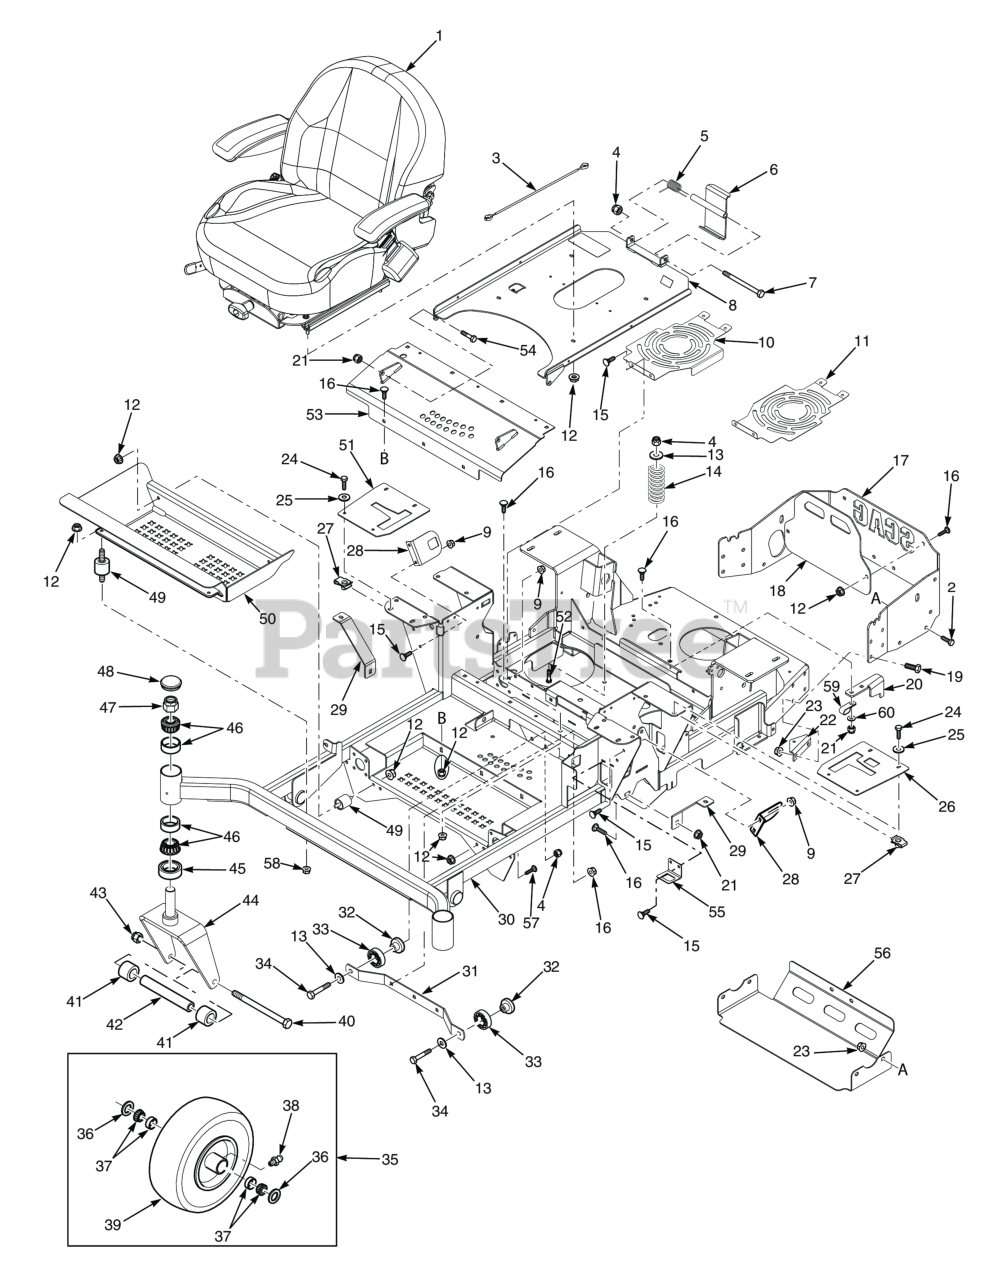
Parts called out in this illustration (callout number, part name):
1	Seat Assembly
2	Capscrew, 3/8-16 x 1.0" Serrated Flange Hex Hd
3	Cable, Seat Stop
4	HEX NUT, ELASTIC STOP LOCK, 3/8-16
5	Spring, Seat Latch
6	Weldment, Seat Latch
7	Bolt, 3/8-16 x 6.00" Hex Head
8	Seat Plate Weldment
9	NUT, 1/4-20 SERRATED FLANGE HEX HEAD
10	Fan Cover, RH
11	Fan Cover, LH
12	Nut, Serrated Flange 5/16-18 (Right Front Engine Mounting, Briggs and Kohler Only)
13	Flatwasher, 3/8" Special (.391 x .938 x .105)
14	Spring, Seat
15	Bolt, Carriage 1/4-20 x 1/2"
16	Bolt, 5/16-18 x .75 RHSN Carriage
17	Bumper, (Black)
18	Guard, Engine, (Scag Gold)
19	Bolt, Hex Head, 3/8-16 x 1 Gr. 5
20	Bracket, Anti-Rotation
21	HEX NUT, ELASTIC STOP LOCK, 3/8-16
22	Bracket, Dump Mounting
23	NUT, 3/8-16 SERRATED FLANGE HEX HEAD
24	CAP SCREW, 1/4-20 X 1" SERRATED FLANGE HEX
25	Flatwasher, 1/4" (.312 x .750 x .065")
26	Control Plate w/Decal, LH (Black)
27	Bolt, Hex Head 3/8-16 x 1"
28	Bracket, Switch Mount
29	Bracket, Tank Mount, SFZ61
30	Mainframe Assy., w/Decals (Black)- SPZ61H
31	Support, Deck Guide
32	Spacer, Bearing
33	Bearing
34	Capscrew, Hex Head 3/8-16 x 2-1/2"
35	Wheel Assembly, (Black)
36	Roller Bearing, Short
37	Bearing, Tapered Roller
38	Fitting, Grease
39	Tire, 13 x 6.50 4-Ply (61A, 72A)
40	Bolt, Hex Head 1/2-13 x 9-1/2" (61V & 72A/VS)
41	Spacer, Caster Wheel
42	Sleeve, Caster Wheel (61V, 72A/VS)
43	HEX LOCKNUT, ELASTIC STOP, 1/2-13
44	Yoke Weldment, (Black))
45	Seal, 2.00" O.D. x 1.625" Bore
46	Bearing Set
47	Nut, Elastic Stop 1.0"-14
48	Cap, Grease
49	Rubber Isolator
50	Footplate Weldment, (Black) - SPZ61
51	Control Plate w/Decal, RH (Black)
52	SHORT SQ. NECK CARRIAGE BOLT, 3/8-16 X 1-1/4"
53	Deck Lift Cover w/Decal, (Scag Gold Logo) - SPZ61
54	Capscrew, 3/8-16 x 1.0" Serrated Flange Hex Hd
55	Switch Bracket
56	Heat Shield, (Scag Gold)
57	Bolt, Heax Head 5/16-18 x 1" (48V / 52V)
58	Nut, Flange Head Elastic Stop 5/16-18
59	Cable Clamp, Double
60	Flatwasher, 5/16-.375 x .875 x .083 (35BV & 37BV-EFI)
